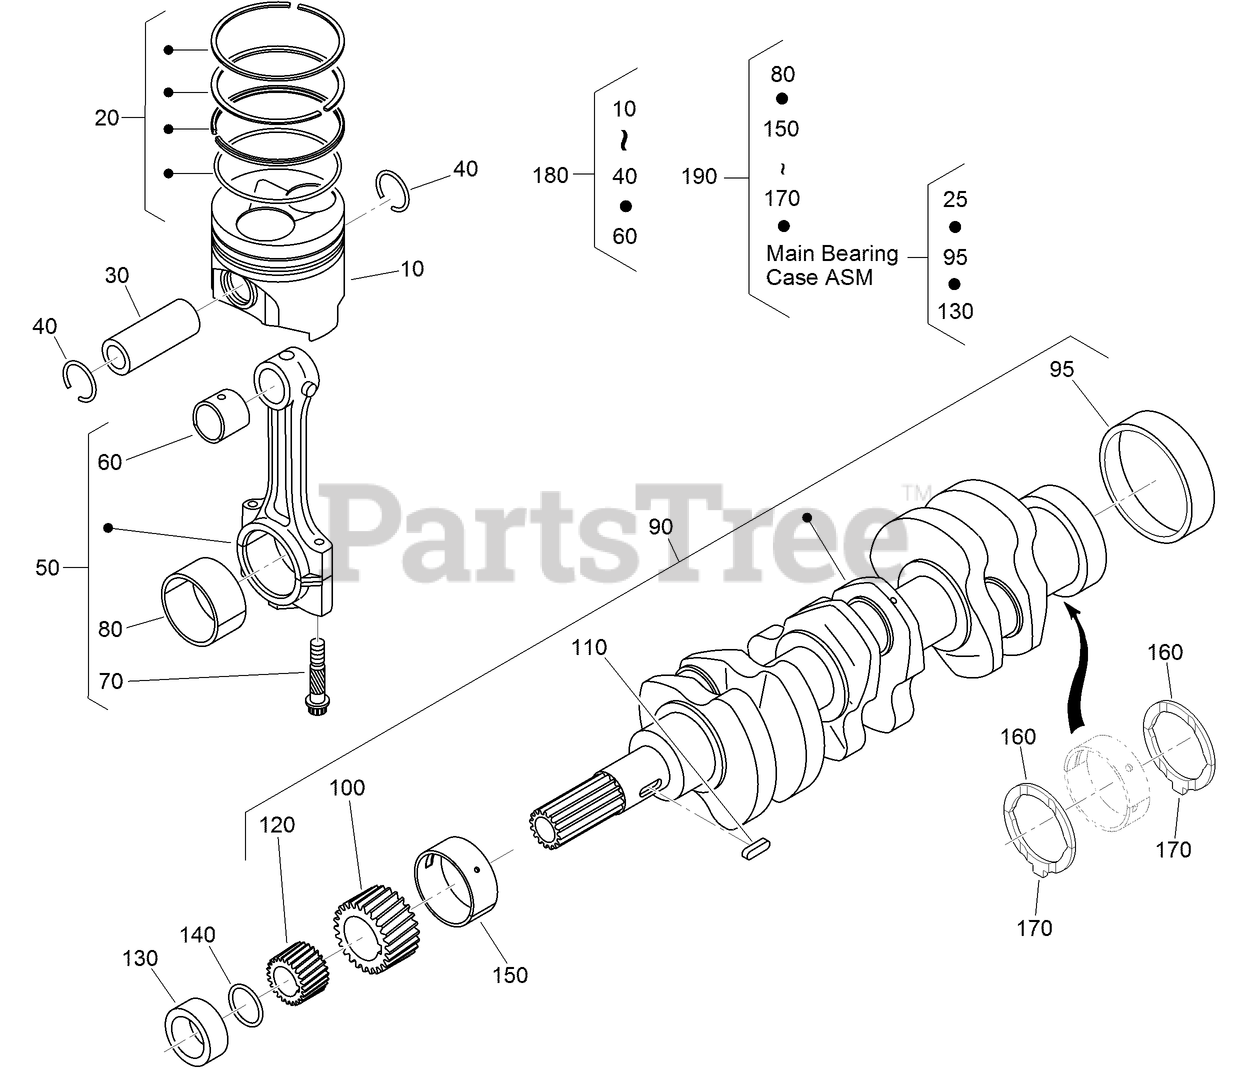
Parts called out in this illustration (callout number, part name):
10	PISTON (STD)
10	PISTON (+0.50MM)
20	PISTON RING ASM (STD)
20	PISTON RING ASM (+0.50MM)
30	PIN-PISTON
40	CIRCLIP-PIN, PISTON
50	CONNECTING ROD ASM
60	BUSHING-PIN, PISTON
70	BOLT-ROD, CONNECTING
80	BEARING-ROD (STD)
80	BEARING-ROD (-0.2MM)
80	METAL-CRANKPIN (-0.4MM)
90	CRANKSHAFT ASM
95	SLEEVE-CRANKSHAFT
100	GEAR-CRANKSHAFT
120	GEAR-DRIVE, OIL PUMP
130	COLLAR-CRANKSHAFT
140	O-RING
150	METAL-CRANKSHAFT
160	BEARING-THRUST (STD)
160	METAL-SIDE (+0.2MM)
160	METAL-SIDE (+0.40MM)
170	BEARING-THRUST (STD)
170	METAL-SIDE (+0.2MM)
170	METAL-SIDE (+0.40MM)
180	PISTON KIT
190	ENGINE METAL KIT
